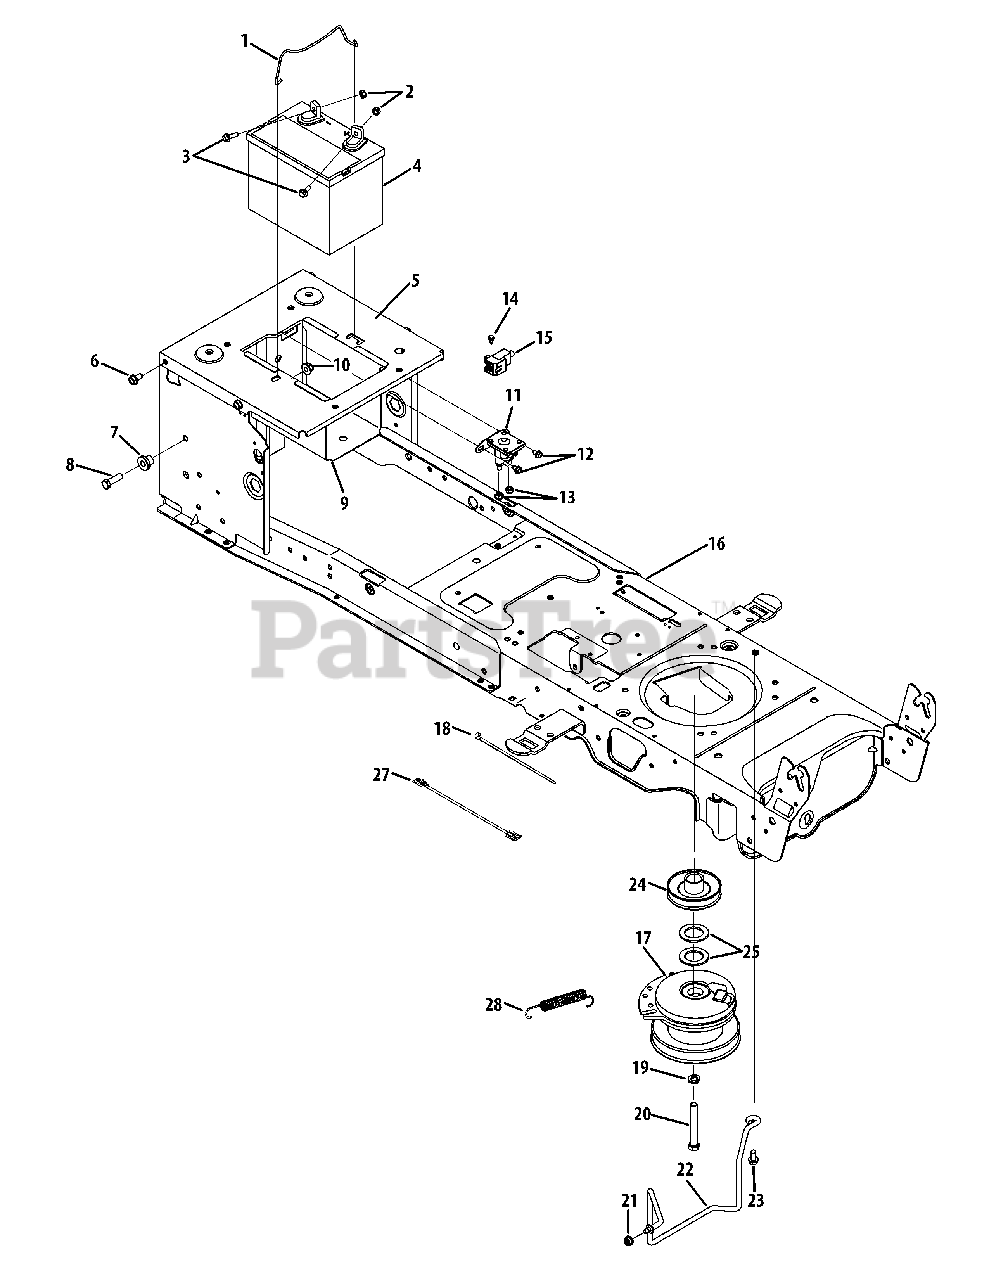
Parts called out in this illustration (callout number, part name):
1	Battery Hold Down Rod
2	Sems Hex Nut 1/4-20
3	Hex Hd. Flg. Scr. 1/4-20 x .75 Gr. 5
4	Battery
5	Seat Frame Bracket
6	SCREW 5/16-18 x .750
7	Shoulder Spacer .38 x 1.0 x .70
8	Hex Bolt 3/8-16 x 1.25
9	Battery Tray
10	Flange Lock-Nut 3/8-16 Gr. F Ny lon
11	Solenoid
12	Hex Flg. Tapp Scr 1/4-20 x .75
13	Hex L-Flanged Nut 1/4-20 Gr. F Nylon
14	Shoulder Screw #10-32 x .50
15	Switch, Interlock
16	Lower Frame Ass'y
17	Electric PTO Clutch (46"/50")
17	Electric PTO Clutch (54")
18	Cable Tie
19	Flat Washer .450 x 1.25 x .164
20	Hex Screw 7/16-20 x 3.5 Gr. 5
21	Flange Locknut 5/16-18 Gr. F, Nylon
22	Keeper Rod (50" & 54")
23	SCREW 5/16-18 x .750
24	Engine Pulley
25	Flat Washer 1.03 ID x 1.64 OD x .095
26	Ext. Spring .5 OD x 5.52" Lg. (50" & 54")
27	Jumper Clutch Harness (46" & 50")
28	Extension Spring
